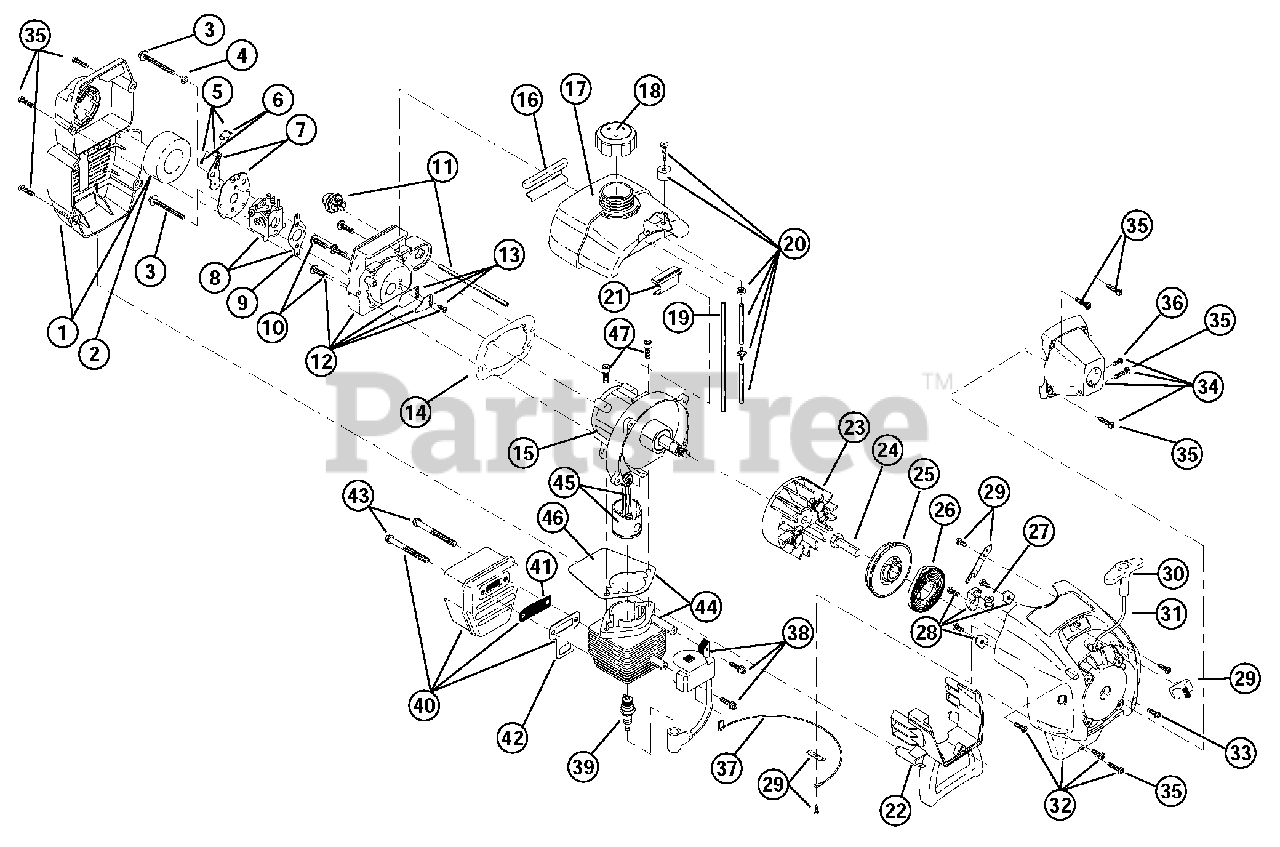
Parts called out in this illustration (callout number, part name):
1	Air Cleaner/Muffler Cover Assembly
2	Air Cleaner Filter
3	Carburetor Mounting Screw Assembly
4	Wavey Washer
5	Choke Lever Assembly
6	Choke Knob and Screw
7	Choke Lever and Plate
8	Carburetor Assembly
9	Carburetor Gasket
10	Carb Mount Screw
11	Primer and Hose Assembly
12	Carb Mount Assembly
13	Reed Assembly
14	Carburetor Mount Gasket
15	Crank Case Service Assembly
16	Rear Mounting Pad
17	Fuel Tank Assembly
18	Fuel Cap Assembly
19	Fuel Return Line
20	Fuel Line Assembly
21	Front Mounting Pad
22	Shroud Extension and Stand
23	Flywheel Assembly
25	Recoil Pulley Assembly
26	Recoil Spring
27	Rope Guide
28	Pulley Retainer Assembly
29	Switch Assembly
30	Pull Handle
32	Starter Housing Assembly
33	Housing Screw
34	Clutch Cover Assembly
36	Anti-Rotation Screw
37	Wire Lead
38	Module Assembly
39	Spark Plug
40	Muffler Assembly
41	Spark Arrestor Screen
42	Exhaust Gasket
43	Muffler Mounting Bolt Assembly
44	Cylinder Assembly
45	Piston and Rod Assembly
46	Cylinder Gasket
47	Cylinder Bolt
